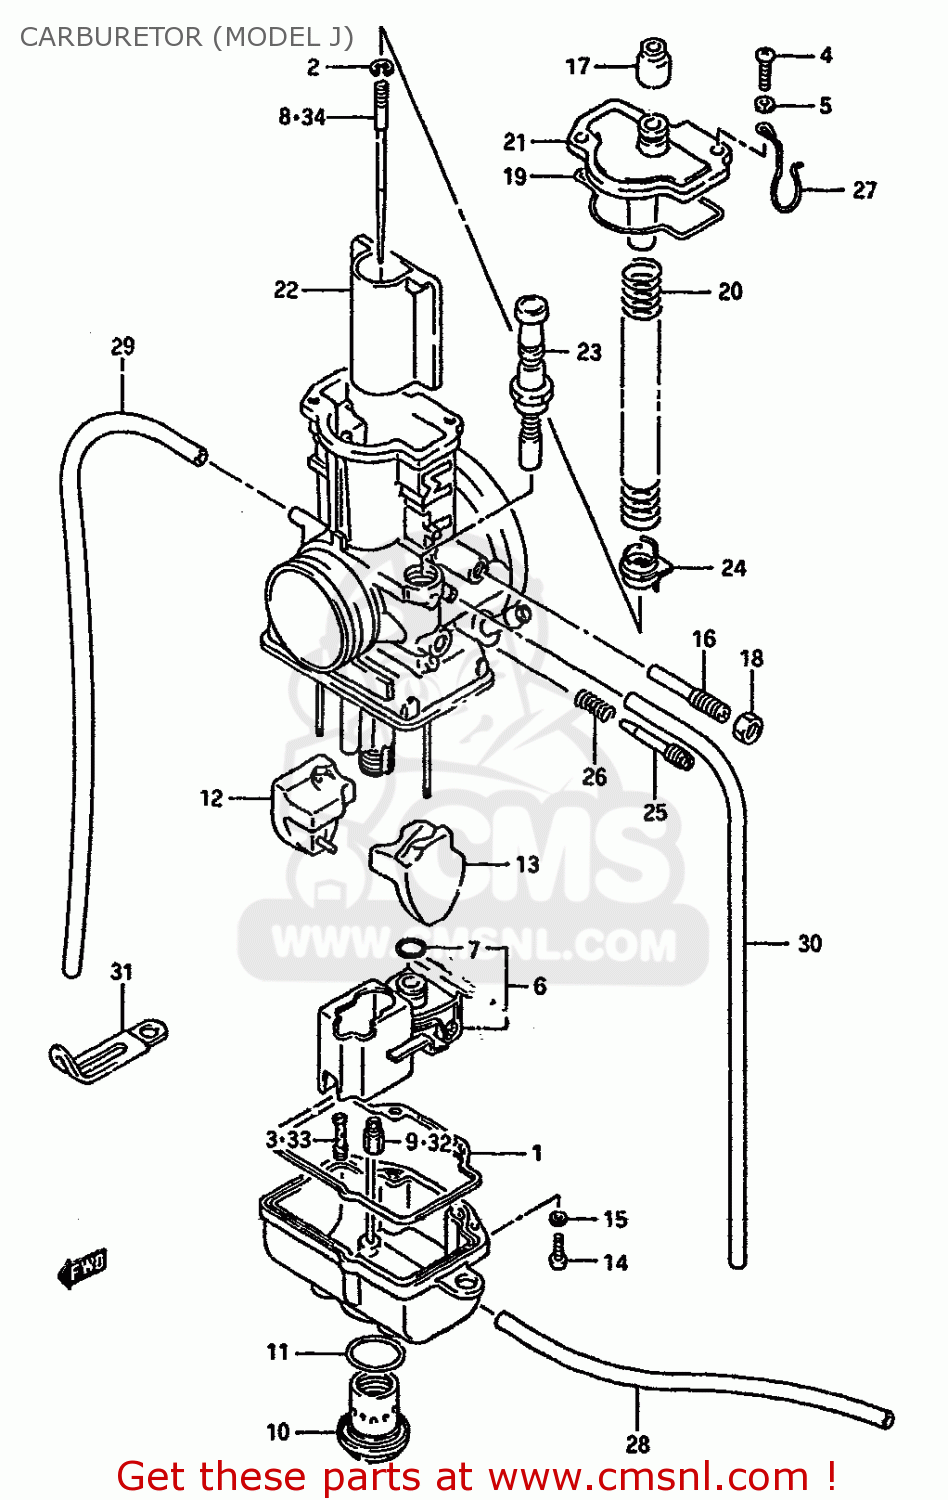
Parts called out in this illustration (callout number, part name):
1	O RING,FLOAT CHAMBER
2	CLIP,NEEDLE
3	JET,PILOT 20
4	SCREW
5	LOCK WASHER
6	VALVE ASSY,NEEDLE
7	O-RING,NEEDLE VALVE
8	NEEDLE JET
9	JET,MAIN(350)
10	CAP,DRAIN
11	O RING,DRAIN PLUG
12	FLOAT,R
13	FLOAT,L
14	SCREW
15	LOCK WASHER
16	ADJUSTER
17	CAP
18	NUT
19	O RING,TOP CAP
20	SPRING
21	CAP,TOP
22	VALVE
23	PLUNGER ASSY
24	RING
25	SCREW,AIR
26	SPRING
27	CLIP
28	HOSE
29	HOSE
30	HOSE
31	CLAMP
32	JET,MAIN(310)
33	JET,PILOT(15)
34	NEEDLE JET
44	JET,NEEDLE
45	JET,PILOT
46	JET,NEEDLE
47	JET,PILOT 20
